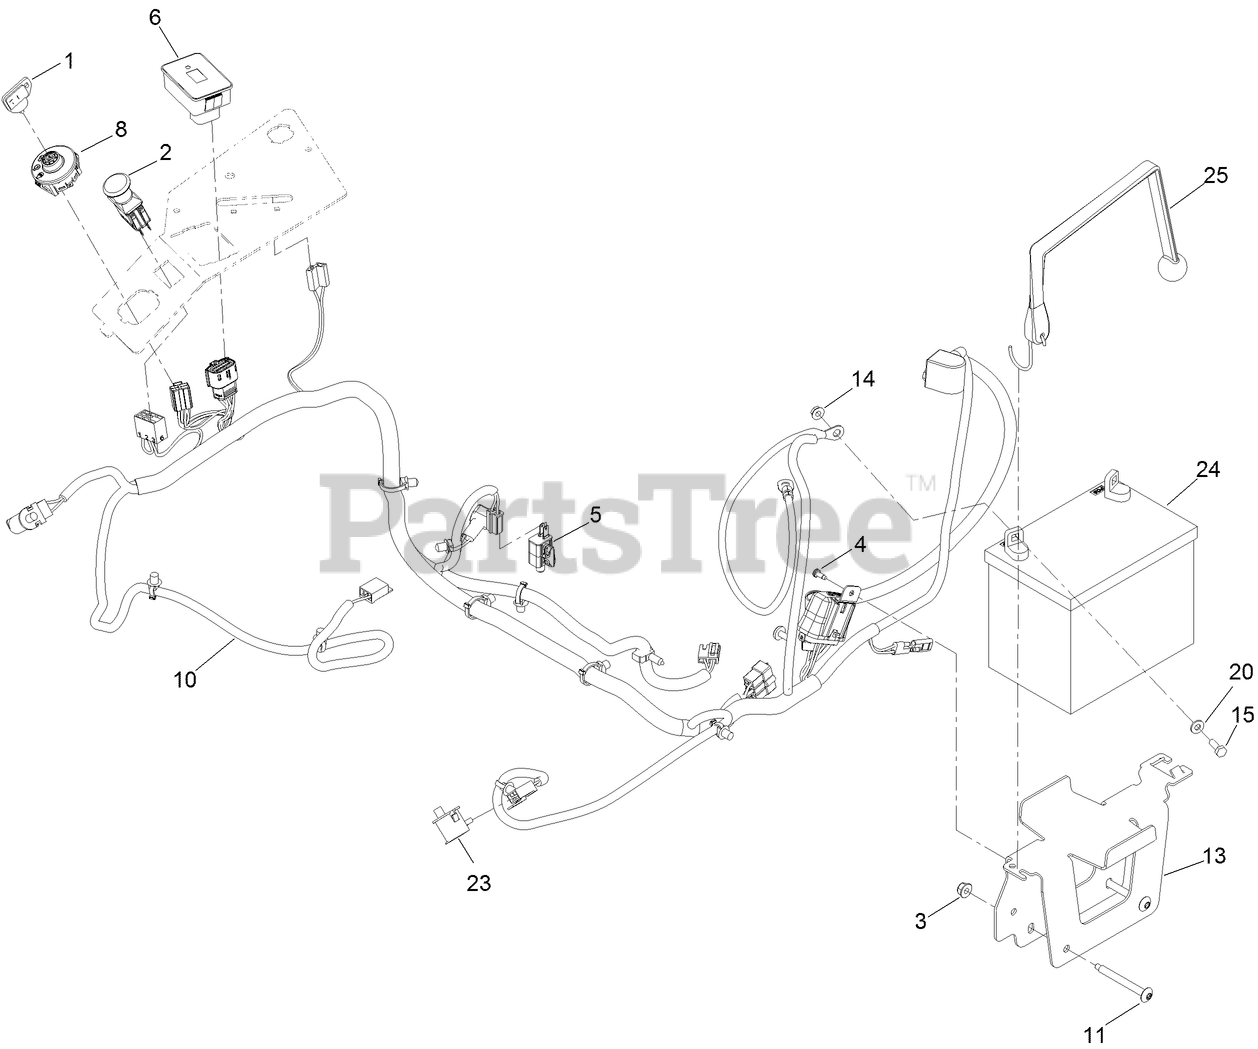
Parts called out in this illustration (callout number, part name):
1	KEY-IGNITION
2	SWITCH-PTO
3	NUT-HF, NI
4	SCREW-FORMING, THREAD
5	SWITCH
6	MODULE ASM
8	SWITCH-IGNITION
10	HARNESS-WIRE
11	SCREW-TORX
13	TRAY-BATTERY
14	NUT-HF
15	SCREW-HH
20	WASHER-FLAT
23	SWITCH-BAIL
24	BATTERY
25	STRAP-BUNGEE
